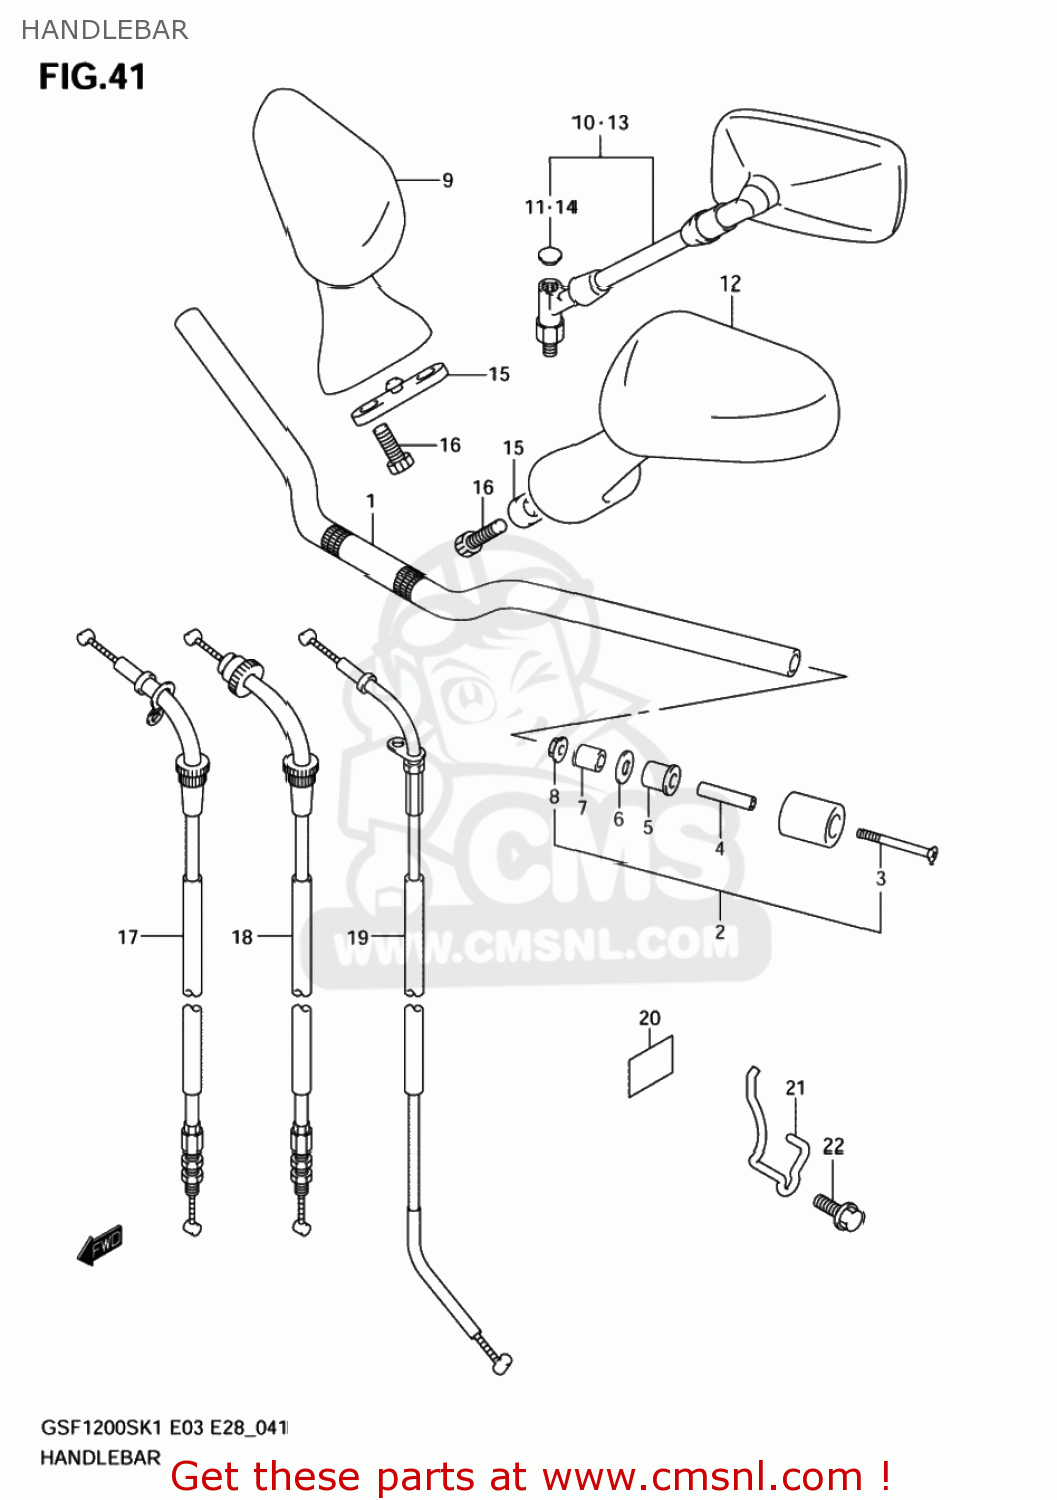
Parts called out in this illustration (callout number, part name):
1	HANDLEBAR
2	BALANCER SET,HANDLEBAR
3	SCREW(6X125)
4	SPACER,EXPANDER
5	EXPANDER,HANDLE BALANCER
6	WASHER
7	EXPANDER,HANDLE
8	NUT
9	MIRROR ASSY,RR VIEW,R
10	MIRROR ASSY,RR VIEW,R
11	CAP
12	MIRROR ASSY,RR VIEW,L
13	MIRROR ASSY,RR VIEW,L
14	CAP
15	CUSHION,RR VIEW MIRRORR
16	BOLT
17	CABLE ASSY,THROTTLE NO.1
18	CABLE ASSY,THROTTLE NO.2
19	CABLE,STARTER
20	PROTECTOR,FRAME COVER FR
21	GUIDE,CABLE
22	BOLT
